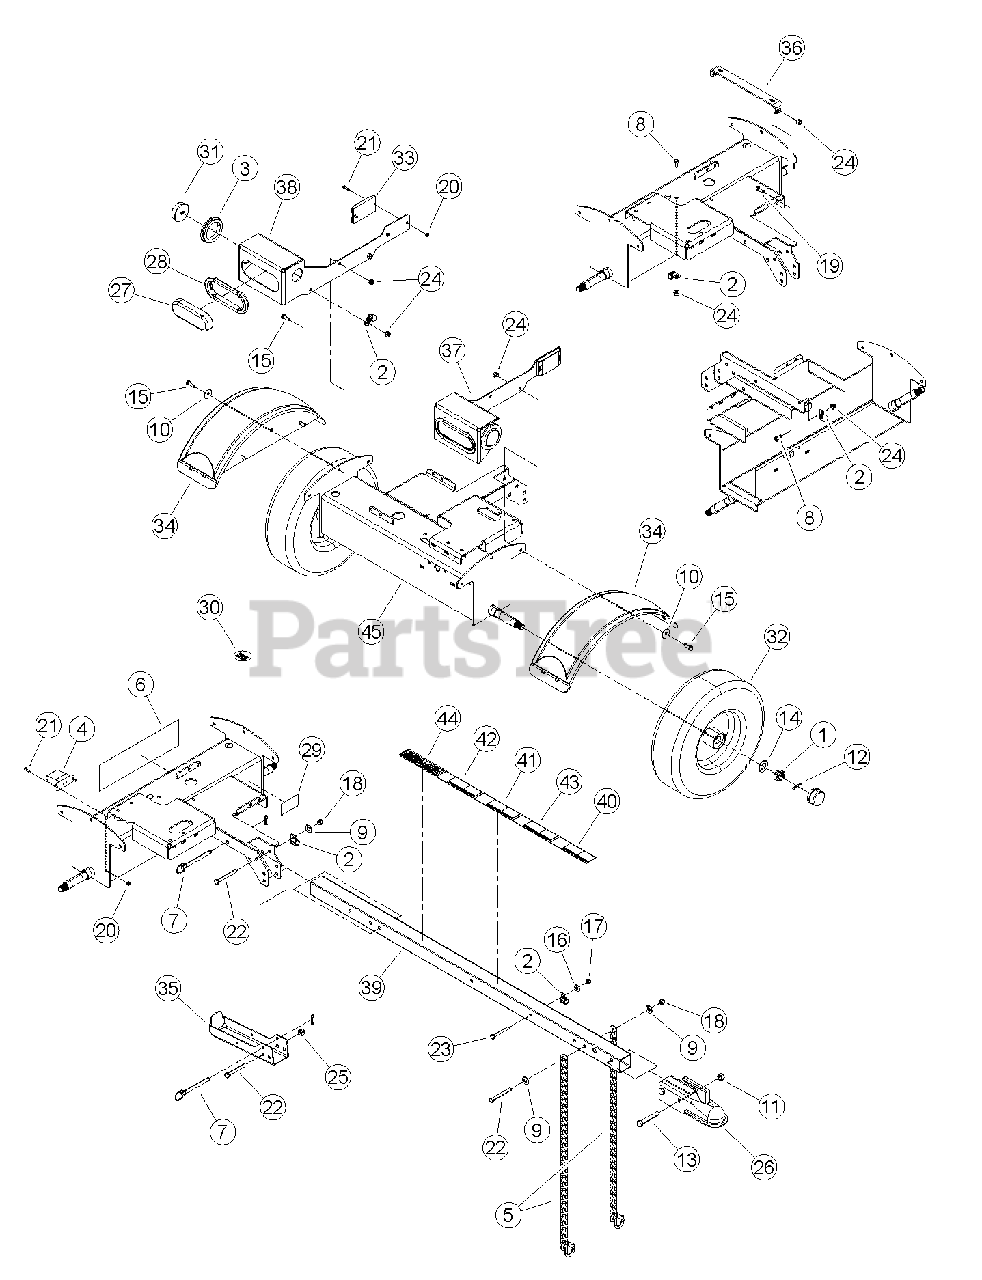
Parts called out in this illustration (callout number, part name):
1	NUT, 3/4 NF HEX SLOTTED ZP
2	CLAMP, 9/16 COATED
3	GROMMET, CLEARANCE LIGHT
4	LIGHT, LICENSE PLATE
5	CHAIN, SAFETY 5000 LB W/ LATCH
6	DECAL, ECHO BEARCAT 14.12 X 4.00
7	PIN, 3/8 HITCH
8	BOLT, 5/16-18 X 3/4 GR5 HEX HD
9	WASHER, 3/8 FLAT
10	WASHER, 5/16" FENDER ZP
11	NUT, 1/2-13 GR5 CENTERLOCK GRB
12	PIN, 5/32 X 1-1/4 COTTER PIN ZP
13	BOLT, 1/2 X 3 GR5 HEX HD ZP
14	WASHER, 3/4" SAE FLAT
15	BOLT, 5/16-18 X 1 GR5 HHCS
16	WASHER, 5/16 FLAT
17	NUT, 5/16-18 NE NYLOCK
18	NUT, 3/8-16 NE NYLOCK
19	BOLT, 5/16-18 X 7/8 HHCS GR5
20	NUT, 10/24 NYLOCK TYPE NM ZP
21	SCREW, #10-24 X 3/4" PAN HD PH ZP MCH
22	BOLT, 3/8 X 3-1/4 HEX HD GR5 ZP
23	BOLT, 5/16-18 X 2-3/4 GR5 HCPS
24	NUT, 5/16-18 NYLOCK FLANGE
25	NUT, 3/8-16 NYLOCK FLANGE
26	COUPLER, TRAILER HITCH
27	TAIL LIGHT, OVAL LED
28	GROMMET, OVAL TAIL LIGHT
29	DECAL, 4.80-8 LOAD RATING
30	DECAL, NATM COMPLIANCE
31	LIGHT, CLEARANCE/MARKER RND RED LED
32	ASSEMBLY, TIRE 4.8-8
33	KIT, LED AMBER LIGHT
34	FENDER, BLACK PLASTIC DRILLED
35	STAND, JACK
36	BRACKET, ENGINE BASE
37	BRACKET, RIGHT TAIL LIGHT
38	BRACKET, LEFT TAIL LIGHT
39	ASSEMBLY, HITCH POLE
40	DECAL, SAFETY CHAINS
41	DECAL, TRAILER ELECTRICAL
42	DECAL, CHECK WHEELS
43	DECAL, SAFE COUPLING
44	DECAL, WARNING TOWING SPEED
45	WELDMENT, SC3" TRAILER
